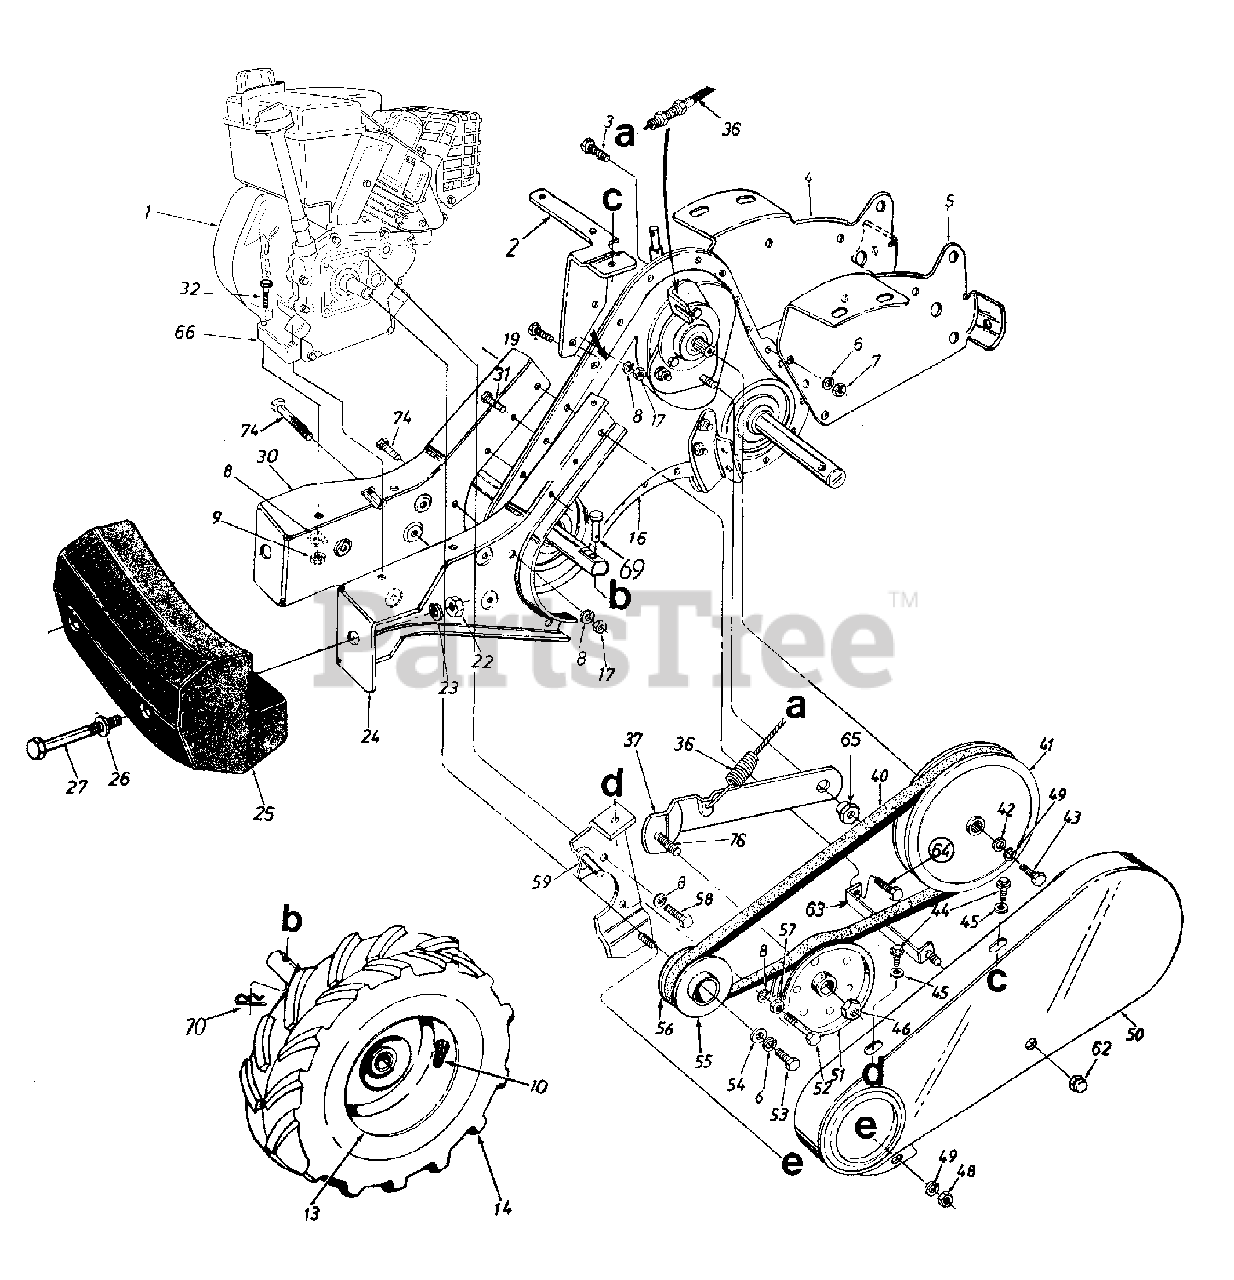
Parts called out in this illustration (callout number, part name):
1	Engine
8	L-Wash. 5/16" I.D.
9	Hex Nut 5/16-18" Thd.
10	Air Valve
16	Gear Case Ass'y. Comp.
17	Hex Nut 5/16-18 Thd.
19	Hex Bolt 5/16-18 x 1" Lg.
22	Hex Nut 1/2-13
23	L-Wash. 1/2" I.D.
26	Fl-Wash. .510" I.D. x 1.0"
27	Hex Bolt 1/2-13 x 5.0" Lg.
32	Hex Bolt 5/16-18 x 2.75"
36	Clutch Control Cable 46" Lg.
37	Idler Bracket
40	"V"-Belt
41	Fl-Pulley 8" O.D.
42	Fl-Wash. 1/4" I.D. x .93" O.D.
43	Hex Bolt 1/4-28 x .75" Lg.
44	Hex Wash. Hd. S-Tap Scr 1/4-20 x .50" Lg.
45	Fl-Wash. .281" I.D. x .625"
46	Center L-Jam Nut 3/8-24 Thd.
48	Hex Nut 1/4-20 Thd.
49	L-Wash. 1/4" I.D.
50	Belt Cover
51	Fl-Idler w/Flanges 3.75" O.D.
52	Hex Bolt 5/16-24 x 1.75"
53	Hex Bolt 3/8-24 x 1.00" Lg.
55	Outer Engine Pulley Half
56	Inner Engine Pulley Half
57	Hex Nut 5/16-24 Thd.
58	Hex Bolt 5/16-24 x .62" Lg.
59	Belt Keeper Ass'y.
62	Hex Cap Nut 1/4-28 Thd.
63	Belt Cover Brkt. Ass'y.
64	Hex Bolt 5/16-18 x 1" Lg. (Gr. 5)
65	Shld. Nut
66	Engine Spacer Block
69	Clevis Pin
70	Hairpin Clip
74	Screw 5/16-18 x 1"
76	Hex Cap Scr. 3/8-16: 1.25 Lg.
